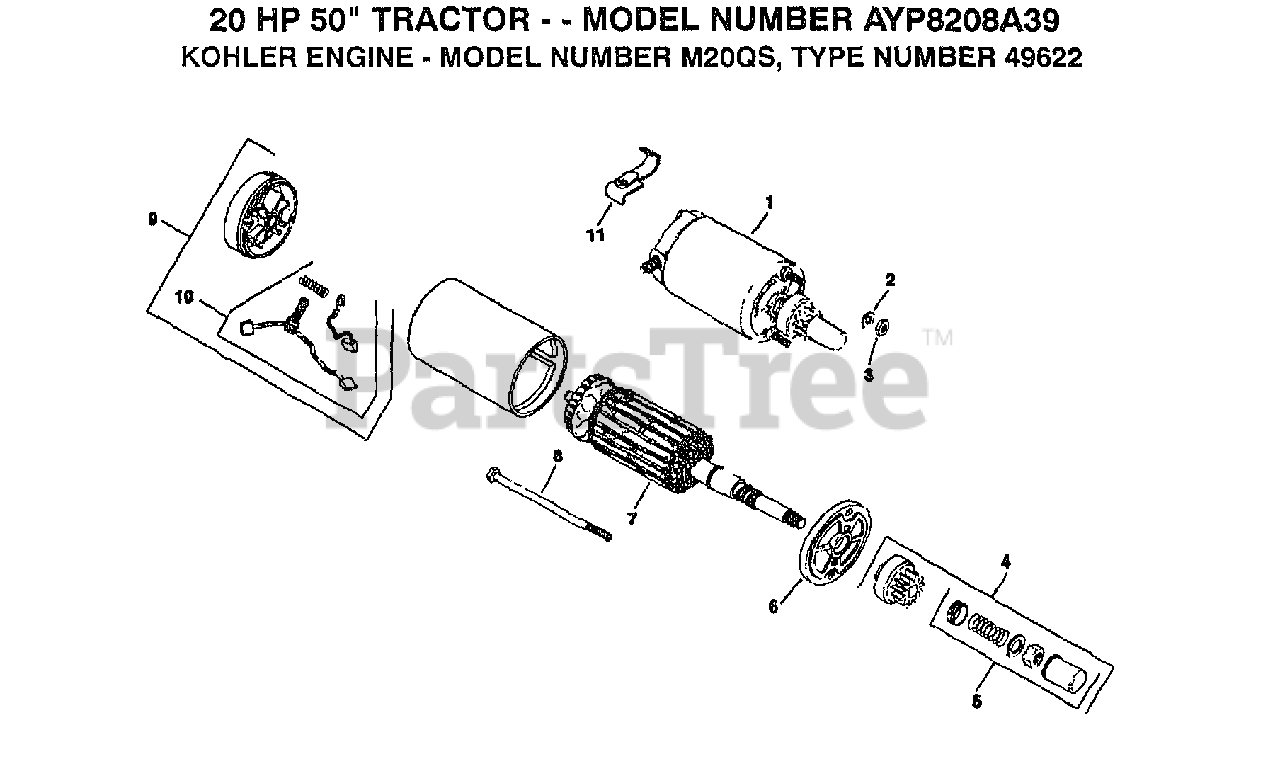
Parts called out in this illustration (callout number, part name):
1	STARTER ASSEMBLY
2	WASHER
3	NUT
5	KIT, DRIVE PARTS
6	CAP, DRIVE END
9	CAP, COMMUTATOR END
11	BRACKET, MOUNTING
